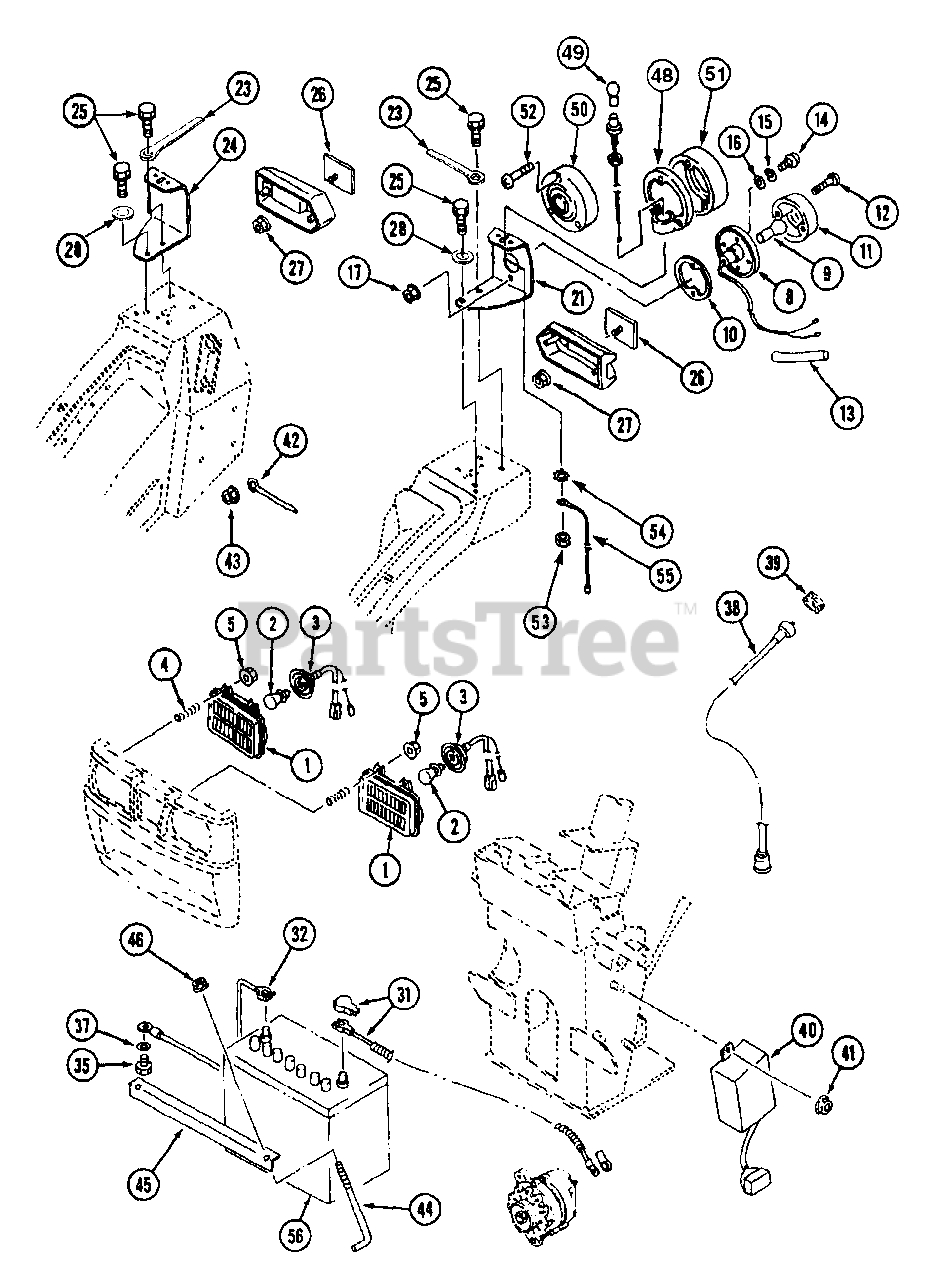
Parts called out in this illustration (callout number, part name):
1	Unit, Semi Sealed Beam
8	Socket
15	Washer, Spring
21	Bracket, Lamp L.H.
24	Bracket, Lamp R.H.
38	Cable, Flexible
45	Clamp, Battery
52	Screw
54	Washer, Tooth
56	Battery, 500CCA
